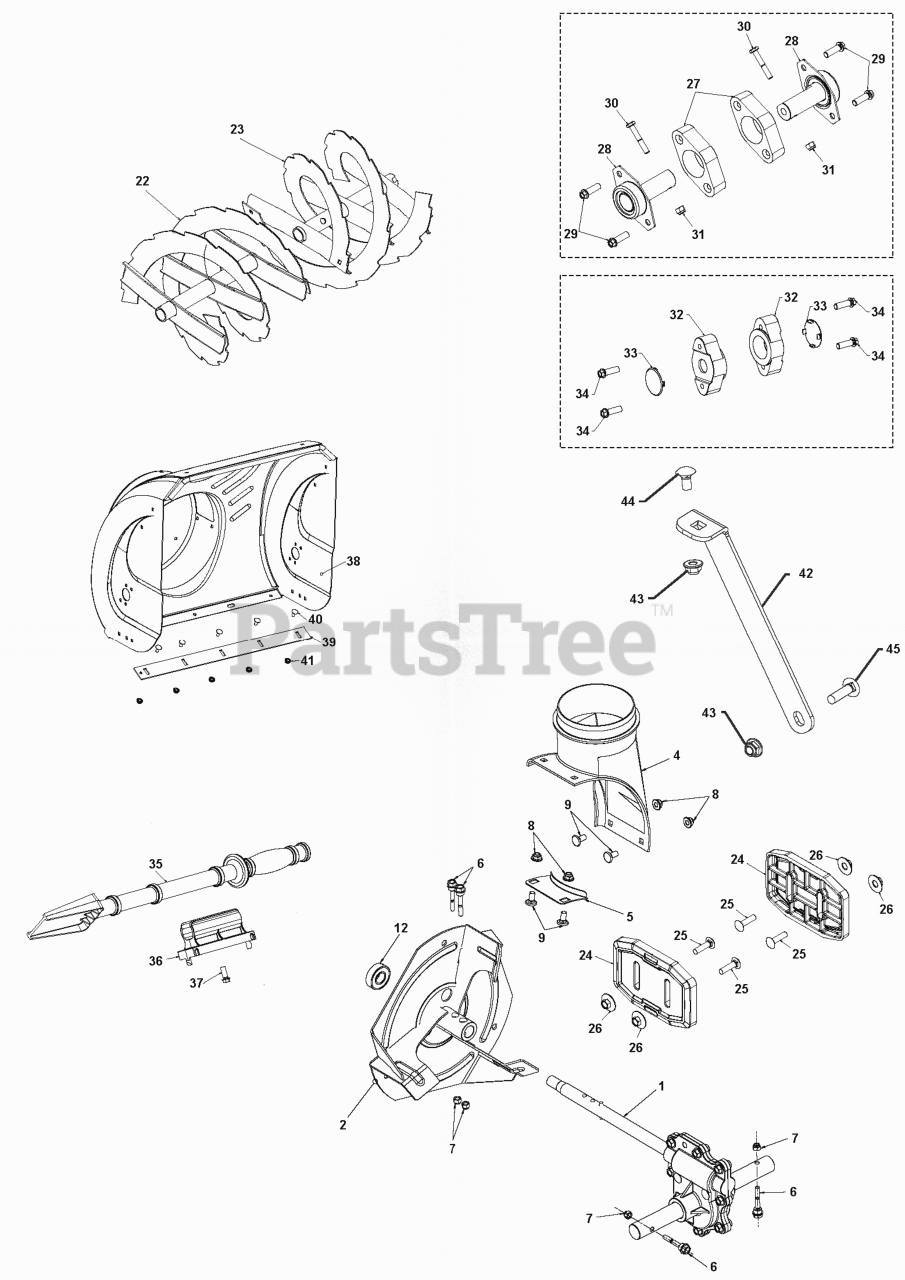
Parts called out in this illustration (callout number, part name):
2	IMPELLER.STEEL.SNOW.BLACK
4	CHUTE.DISCHARGE.BASE
6	BOLT SHEAR HX HD 1/4-20 CLEAR
7	LOCKNUT.NYLOC.1/4-20
7	NUT HEXAGON 1/4-20 ST ZPB
8	NUT HEX FLG NYLOCK BLK 5_16-1
9	BOLT CARR WAFER BLK 5_16-18 X
22	AUGER.WELD.RIB.BUT.RH.30.BLACK
23	AUGER.WELD.RIB.BUT.LH.30.BLACK
24	PLATE.SKID.SHOE.COMPOSITE
25	BOLT CAR BLK 5/16-18 X 1-1/4
26	NUT.HEX.FL 5/16-18 TOP LCK BLK
27	BEARING RETAINER, PLASTIC
28	BEARING.BALL.AUGER.FLAT.
28	BALL BEARING AUGER BALL BEARIN
29	SCREW.HI-LO. 5/16 X 1.00
30	BOLT HEXAGON BOLT 1/4-20 X 1-5
30	SCREW.HEX.HD1/4-20X
31	LOCKNUT.NYLOC.1/4-20
31	NUT HEXAGON 1/4-20 ST ZPB
32	BEARING.AUGER.SHAFT
33	PLUG.BEARING.HOLE.HSG
34	SCREW.HI-LO. 5/16 X 1.00
35	CLEAN OUT TOOL
36	CLIP.CLEANOUT.TOOL
37	SCREW.HWH.13-16-5.8.BZP
38	KIT.AUGER.HOUSING.586184105
39	RP BAR.SCRAPER.30.BLACK
40	BOLT ROUND HEAD SQUARE NECK BO
41	NUT.FLANGE.5/16
42	BRACE SUPPORT GEARBOX 200 SERI
43	NUT HEX FLG NYLOCK BLK 5_16-1
44	BOLT CAR BLK 5/16-18 X 5/8
45	BOLT.CARRIAGE.5/16-18
